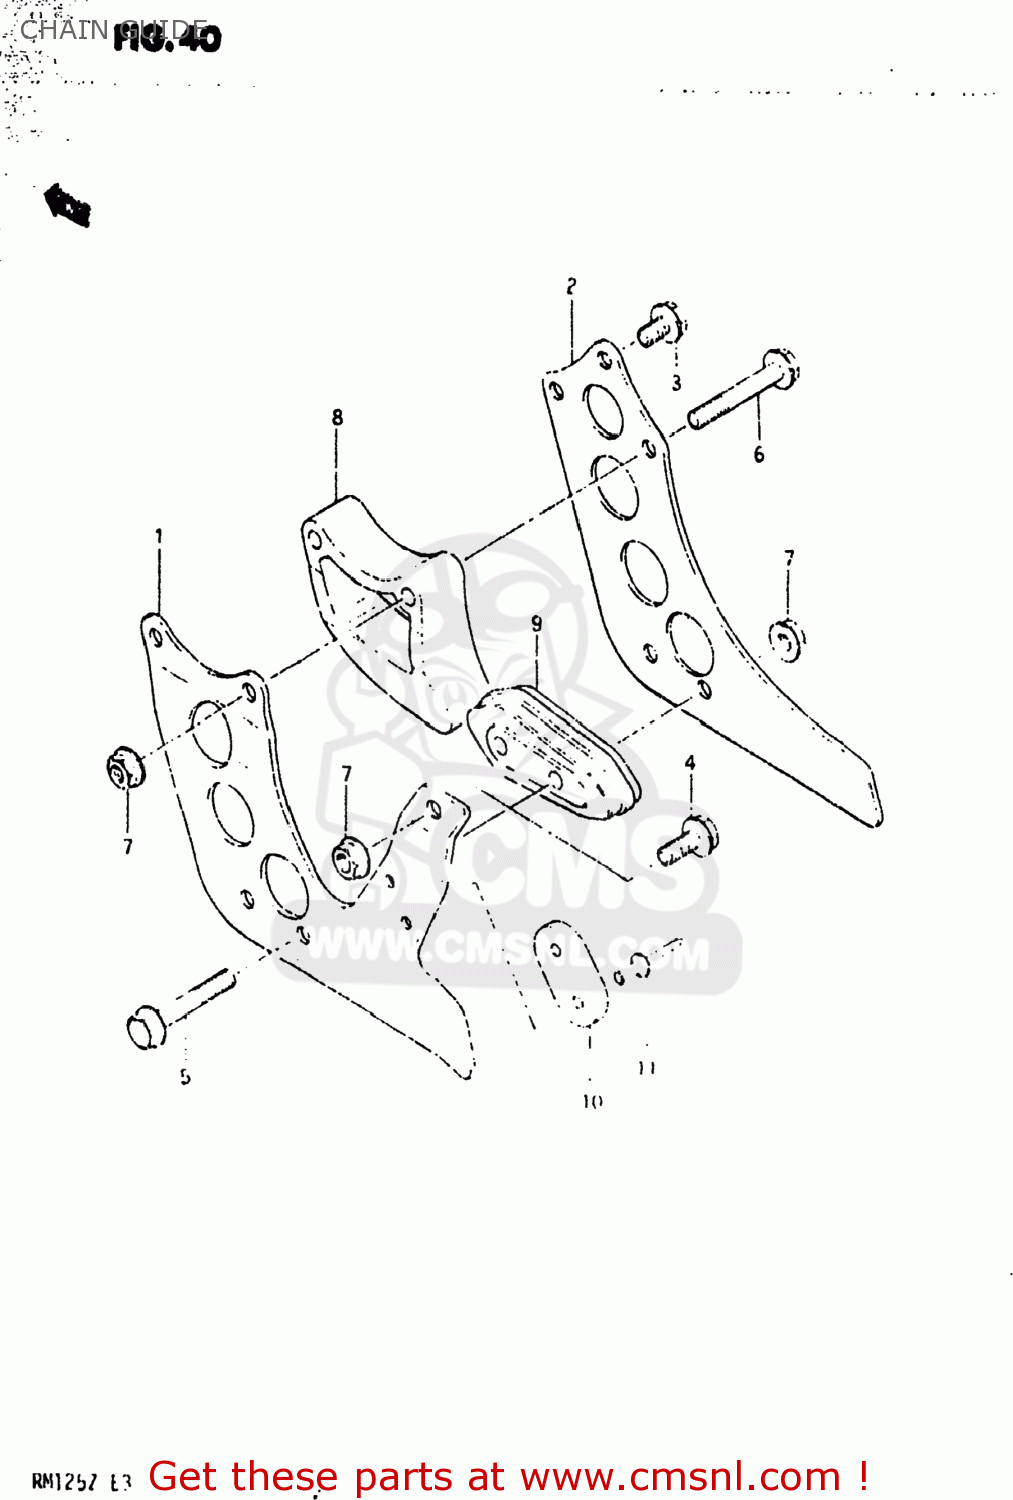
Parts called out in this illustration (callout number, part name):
1	PLATE,CHAIN GUIDE,OUTER
2	PLATE,GUIDE CHAIN
3	BOLT
4	BOLT
5	BOLT
6	BOLT,UNDER
7	NUT
8	DEFENSE,CHAIN GUIDE UPR
9	DEFENSE,CHAIN GUIDE
10	PAD,DRIVE CHAIN GUIDE
11	RIVET
